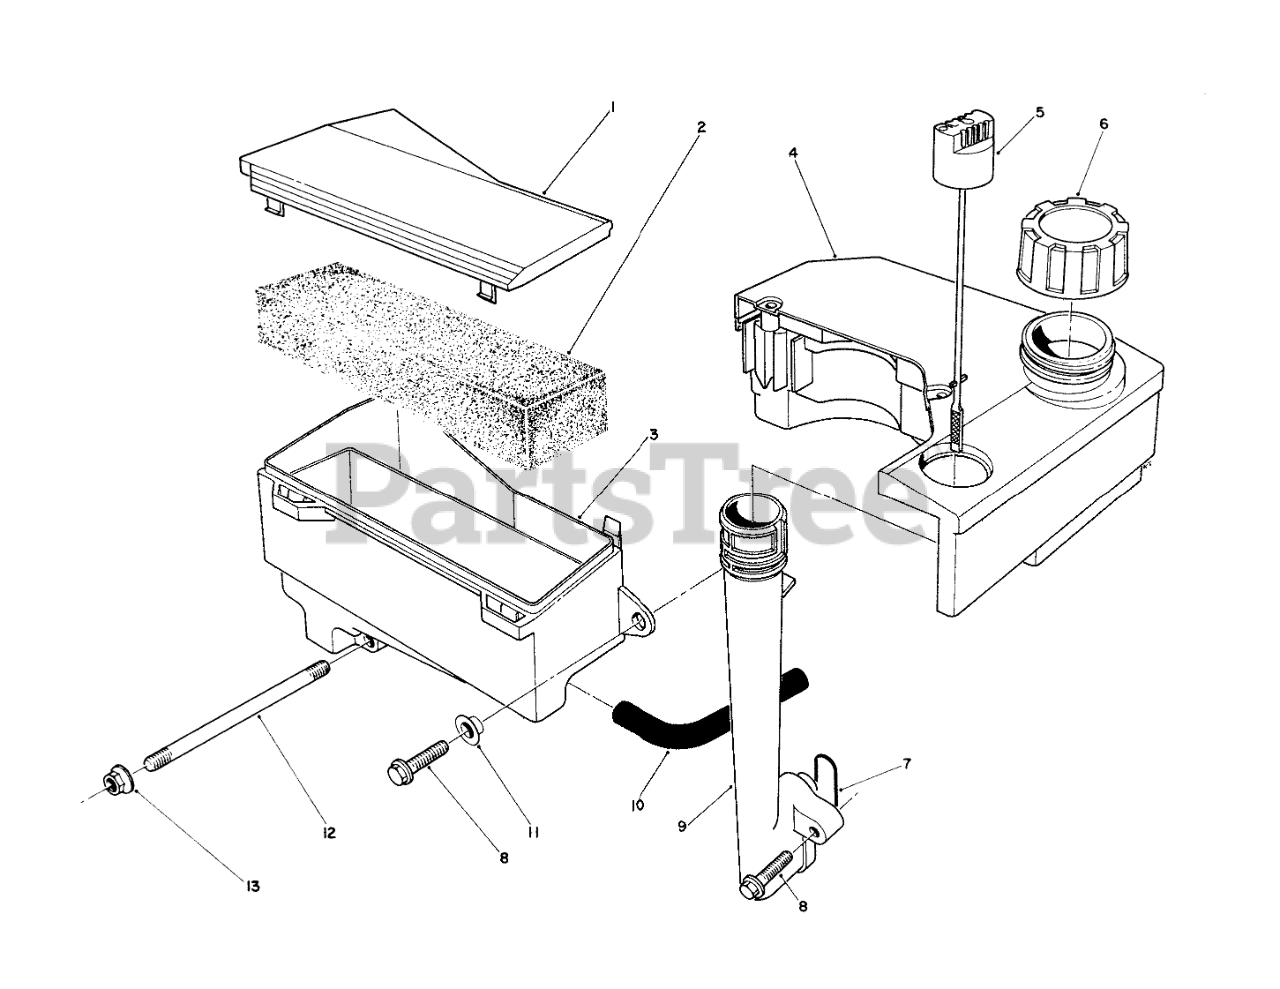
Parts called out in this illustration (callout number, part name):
1	AIR CLEANER CAP
3	Body-Air Cleaner
4	TANK ASM
5	Dipstick
6	GAS CAP ASM
7	O-RING
11	SPACER
12	Stud-Carburetor
